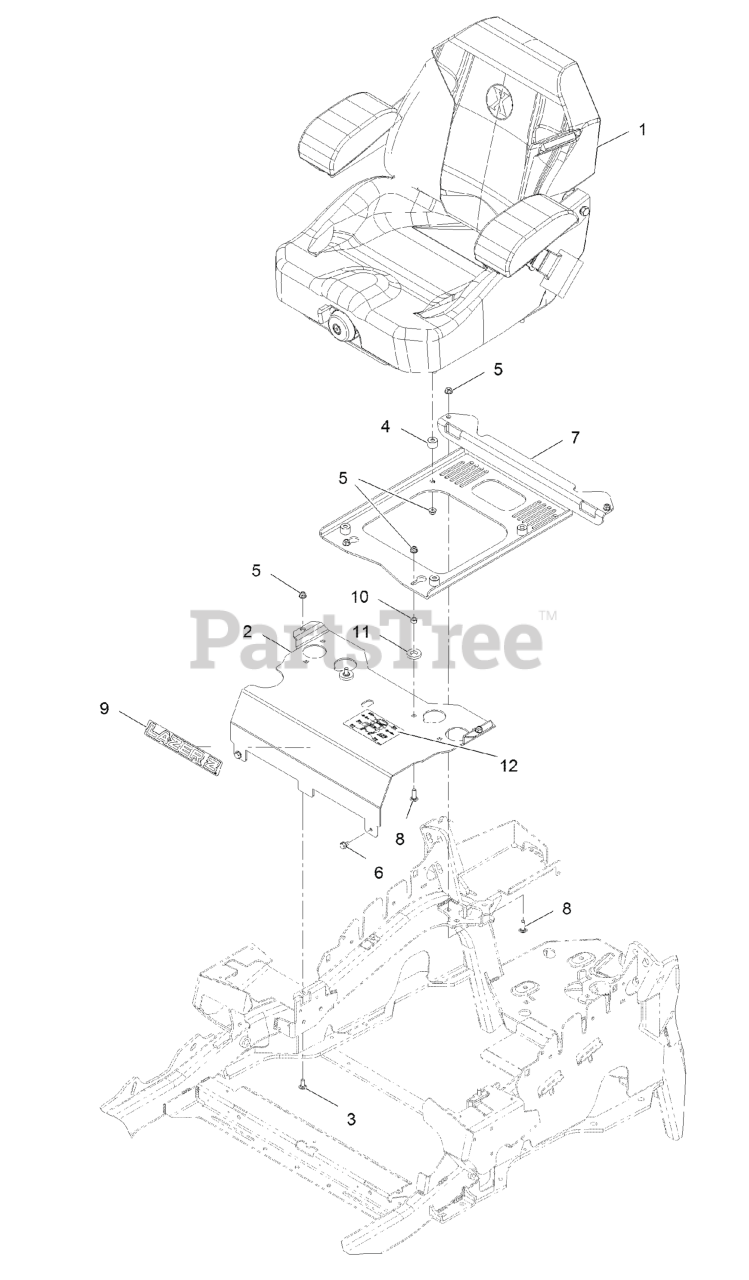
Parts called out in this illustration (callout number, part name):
1	KIT-SUSPENSION SEAT
2	Panel-Front, Seat Mount
3	SCREW-CARR
5	NUT-HF, NI
7	PLATE-SUPPORT, SEAT
8	SCREW-CARR
9	DECAL, LAZER MODEL
10	NUT-HEX
12	DECAL-SERVICE AID
